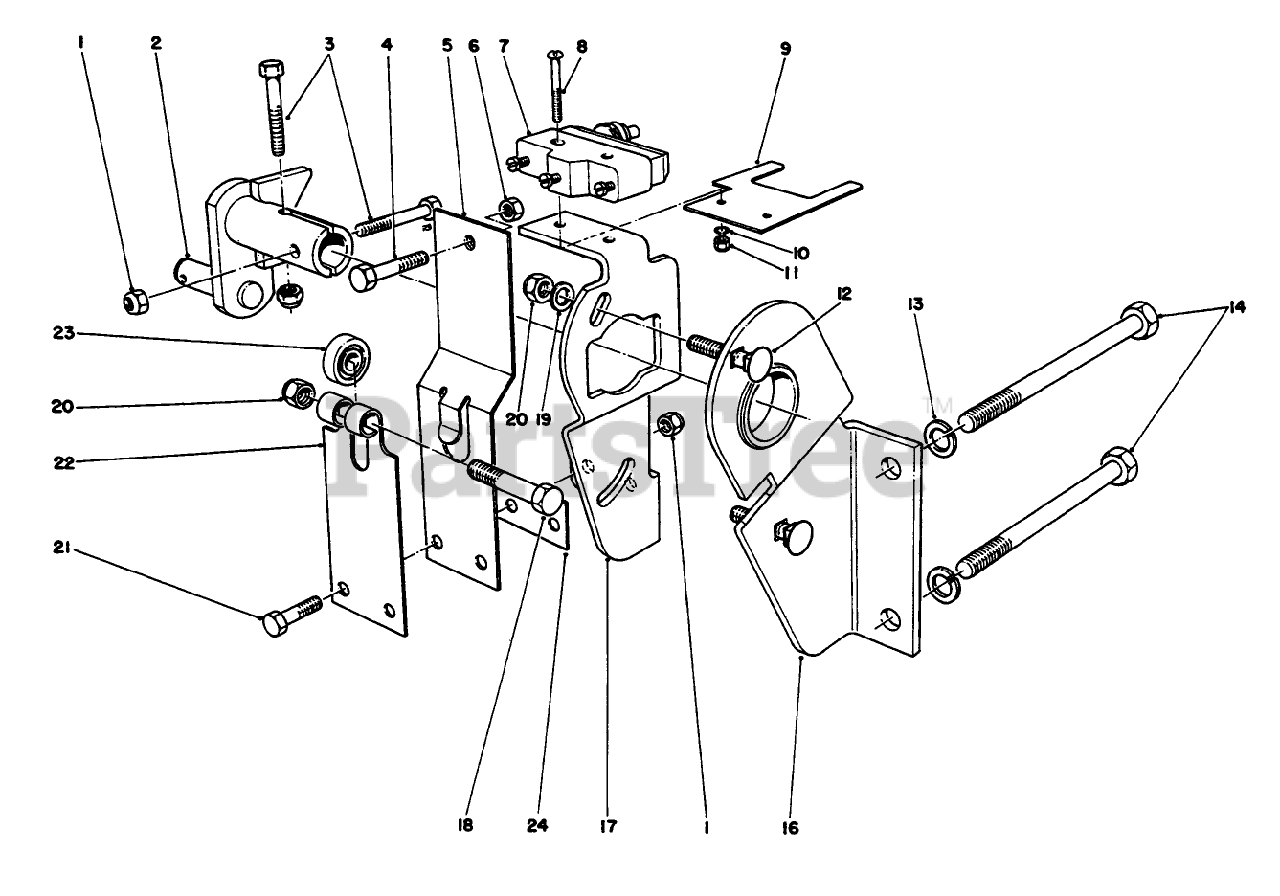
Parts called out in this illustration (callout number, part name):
1	NUT-LOCK, NI
2	Lever-Pump
3	SCREW-HH
4	SCREW-HH
5	EXTENDED LEAF SPRING ASM
6	NUT-HEX
7	SWITCH-MICRO
8	SCREW-MACHINE
9	STOP-SPRING, LEAF
10	WASHER-LOCK, INTERNAL
11	NUT-HEX
12	BOLT-CARR
13	WASHER-LOCK
14	SCREW-HH
16	Bracket-Mounting
17	PLATE-PUMP
18	SCREW-HH
19	WASHER-FLAT
20	NUT-LOCK, NI
21	SCREW-HH
22	SPRING-LEAF
23	BEARING-BALL
25	SHIM-ARM, SPRING
